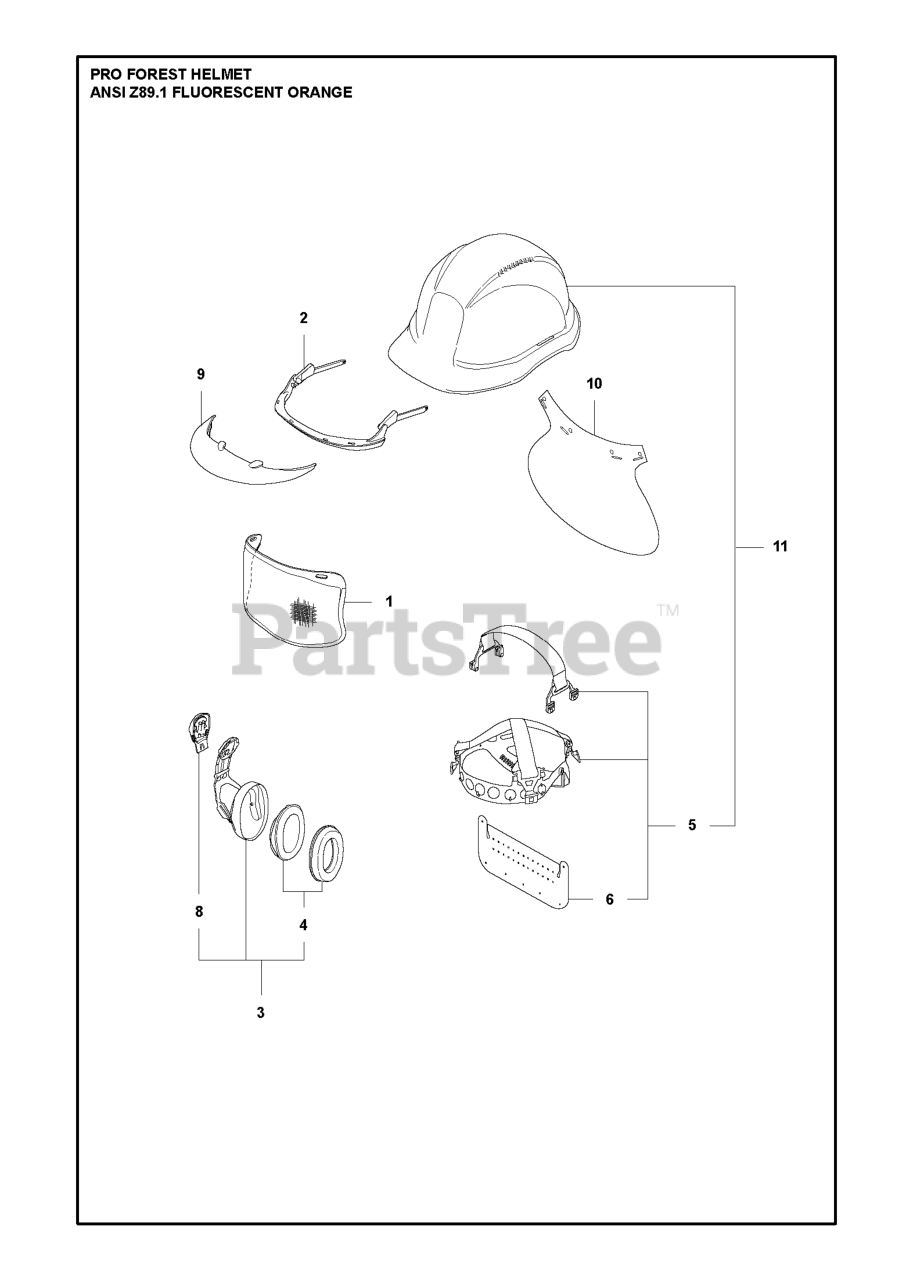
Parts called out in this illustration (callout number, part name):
1	Mesh visor, metal
2	VISOR ARM/HOLDER
3	Hearing Protector set
4	HYGIENE SET
5	SPHARNESS F HELMET H200/BALANC
6	SWEATBAND FOR HELMET
8	HOLDER FOR HEARING PROTECTORS
9	VISOR SHIELD N/A FOR HELMET
10	Rain Protector for neck
11	HUS HARD HAT ORANGE
